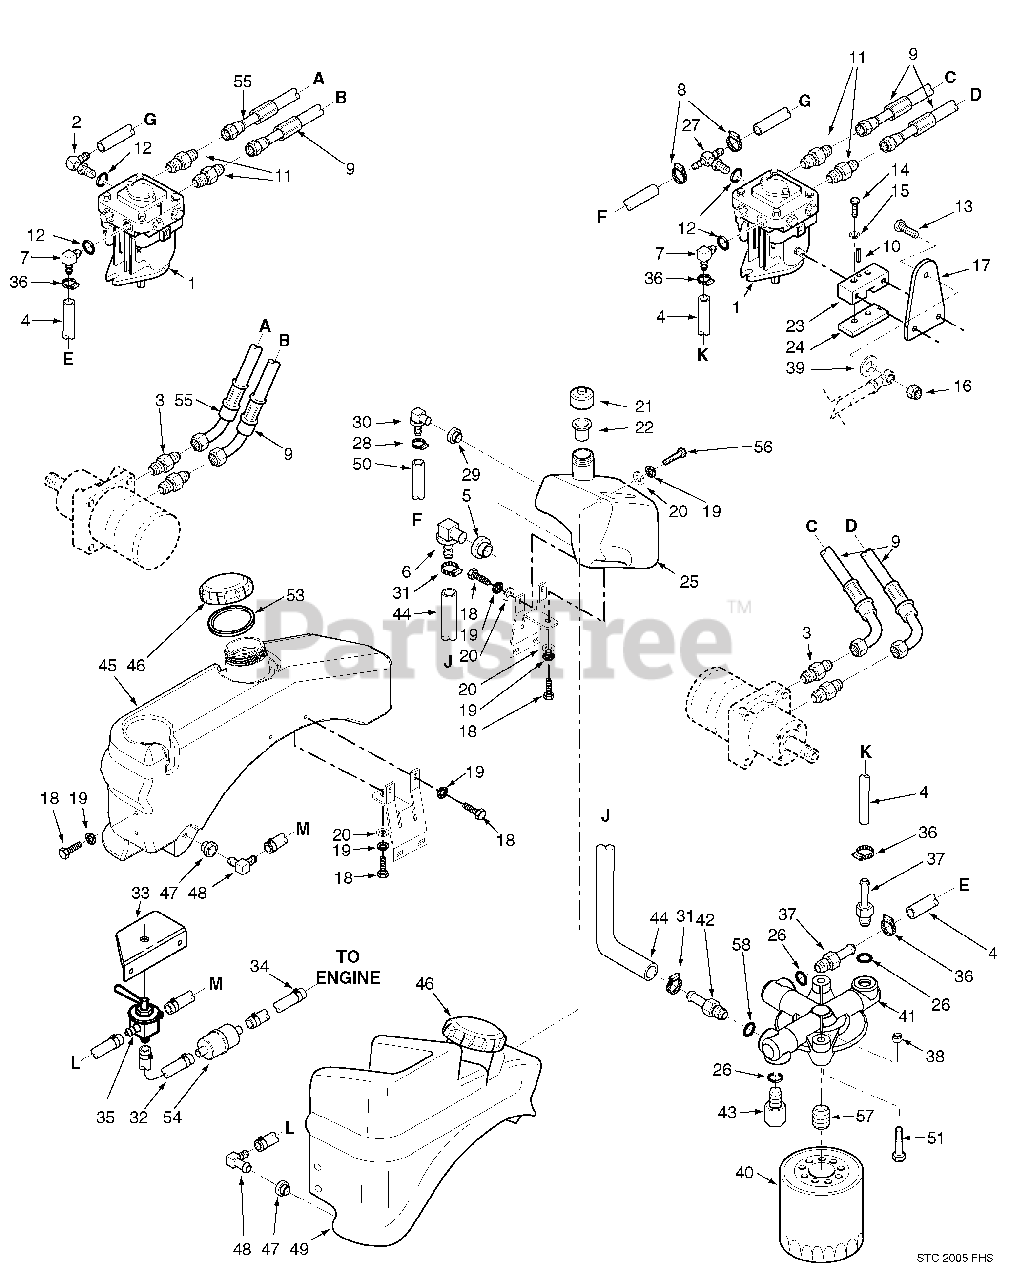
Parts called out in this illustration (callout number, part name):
1	Pump, BDP-10A-316
2	Elbow, 90 Degree 9/16 O-Ring x 3/8 Hose
3	Fitting, 1/2" JIC x 5/8 O-Ring
4	Hose, 3/8 Pushlock
5	Bushing
6	Fitting
7	Elbow, 90 Degree 9/16 O-Ring x 3/8 Hose
8	Hose Clamp, .69 Dia.
9	Hose Assembly
10	Roll Pin
11	Fitting, 1/2" JIC x 1/2" O-Ring
12	O-Ring
13	Bolt, Hex Head 3/8-16 x 1-1/2"
14	Bolt, Hex Head 1/4-20 x 1-1/4"
15	Lockwasher
16	Nut, Elastic Stop 3/8-16
17	Control Lever
18	Bolt, Hex Head 5/16-18 x 3/4"
19	Lockwasher, 5/16
20	Flatwasher, 5/16-.375 x .875 x .083
21	Cap, Hydraulic Tank
22	Insert, Filler Neck
23	Control Block
24	Clamp Plate
25	Hydraulic Tank Assembly w/fittings
26	O-Ring, 9/16"
27	Tee Fitting, O-Ring to Barb
28	Clamp, .69 Max. / .25 Min. Dia.
29	Bushing
30	Elbow, 0.38 Hose
32	Fuel Hose, 1/4 ID
33	Bracket Fuel Valve
34	Clamp, Fuel Hose 1/4 Hose ID
35	Valve, Fuel Shutoff
36	Clamp, .69 Max. / .25 Min. Dia.
37	Fitting, 9/16 O-Ring x 3/8 Hose
38	Nut, Serr. Flange 5/16-18
39	Flatwasher, 3/8-.391 x .938 x .105
40	Oil Filter
41	Filter Head Assembly
42	Fitting, 3/4 O-Ring x 3/8 Hose
43	Plug, 9/16-18 O-Ring
44	Hose, Filter Inlet
45	Fuel Tank RH
46	Cap, Fuel Tank
47	Tank Bushing
48	Elbow, 90 Degree
49	Fuel Tank LH
50	Hose, 3/8 Pushlock 15" Long
51	Bolt, Hex Head 5/16-18 x 2"
52	Screw, 1/4-20 x 2"
53	Gasket, Gas Tank Cap
54	Fuel Filter
55	Hose Assembly
56	Bolt, Hec Head 5/16-18 x 1-1/2
57	Nipple, Oil Filter 1.0-12 UNF-2A x 1-1/4"
58	O-Ring, 3/4"
